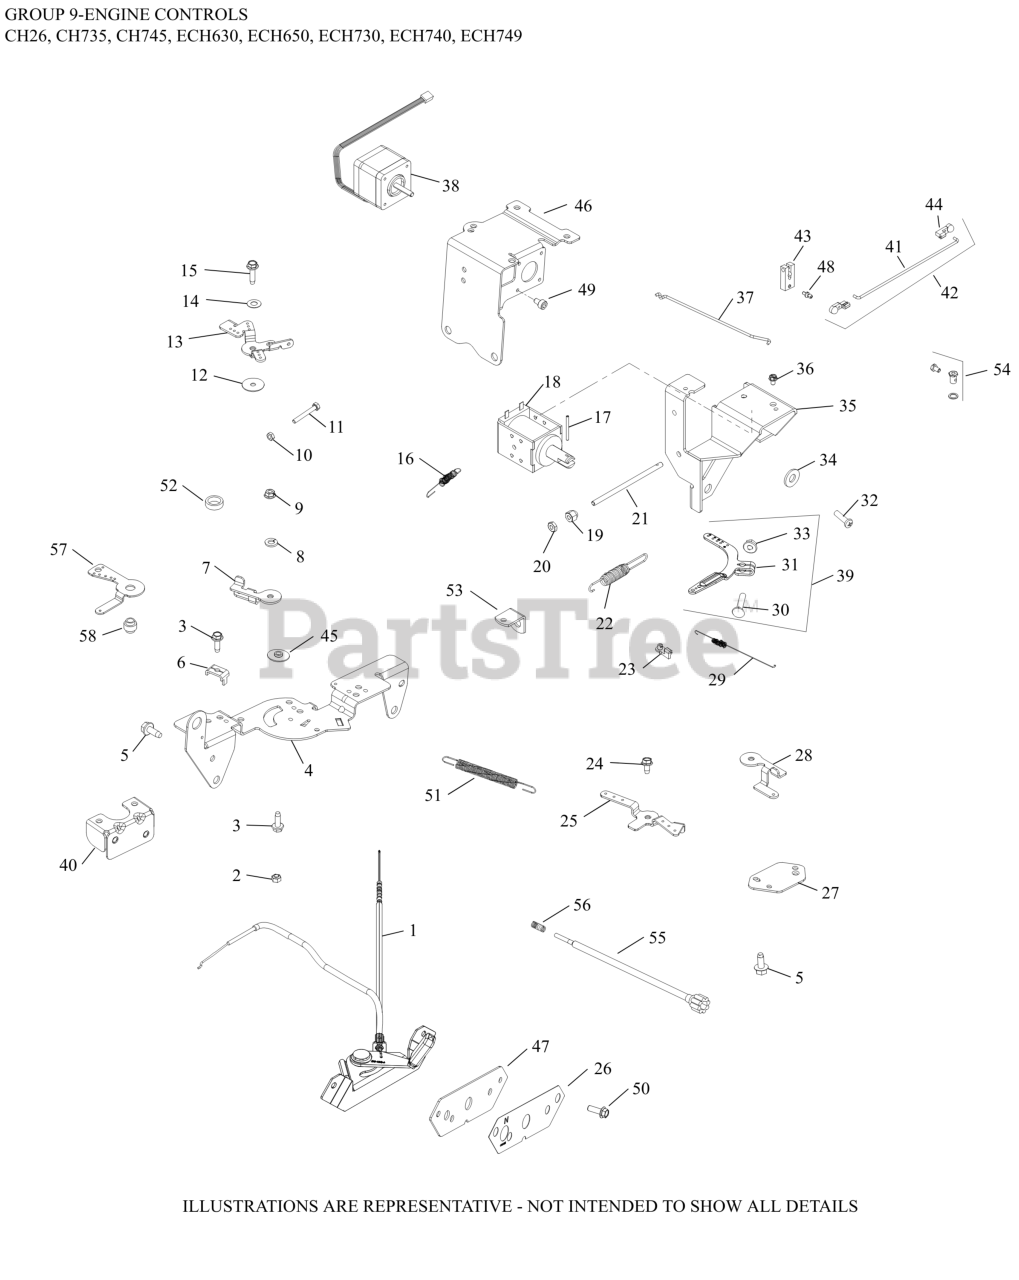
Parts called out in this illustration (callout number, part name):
1	CABLE, CONTROL ASSEMBLY
2	NUT, LOCK M5X.8
3	SCREW, THREAD FORMING
4	BRACKET, CONTROL-(#24126263S)
5	SCREW, THREAD FORMING
6	CLAMP, CABLE-(#2523753S)
8	WASHER, SPRING LOCK 1/4"
9	NUT, FLG M5X.8
10	NUT, M4X0.7
11	SCREW, CAP M4X.7X30
12	WASHER, FLAT 5.5 MM
14	WASHER, SPRING 1/4"
15	SCREW, THD FRM-USE 25 086 473-S
16	SPRING, THROTTLE LIMITER
22	SPRING, GOVERNOR (GREEN)
23	BUSHING, THROTTLE LINKAGE
24	SCREW, THREAD FORMING
25	LEVER, THROTTLE CONTROL
26	LABEL, CONTROL PANEL
27	BRACKET, CABLE SUPPORT
28	LEVER, THROTTLE ACTUATOR
29	SPRING, LINKAGE
30	BOLT, RD HD SQ NECK M6X1.0X25
31	LEVER, GOVERNOR - (#2409069S)
33	NUT, FLG M6X1.0
37	LINKAGE, THROTTLE
39	LEVER, GOVERNOR ASSEMBLY
50	SCREW, HI-LOW
